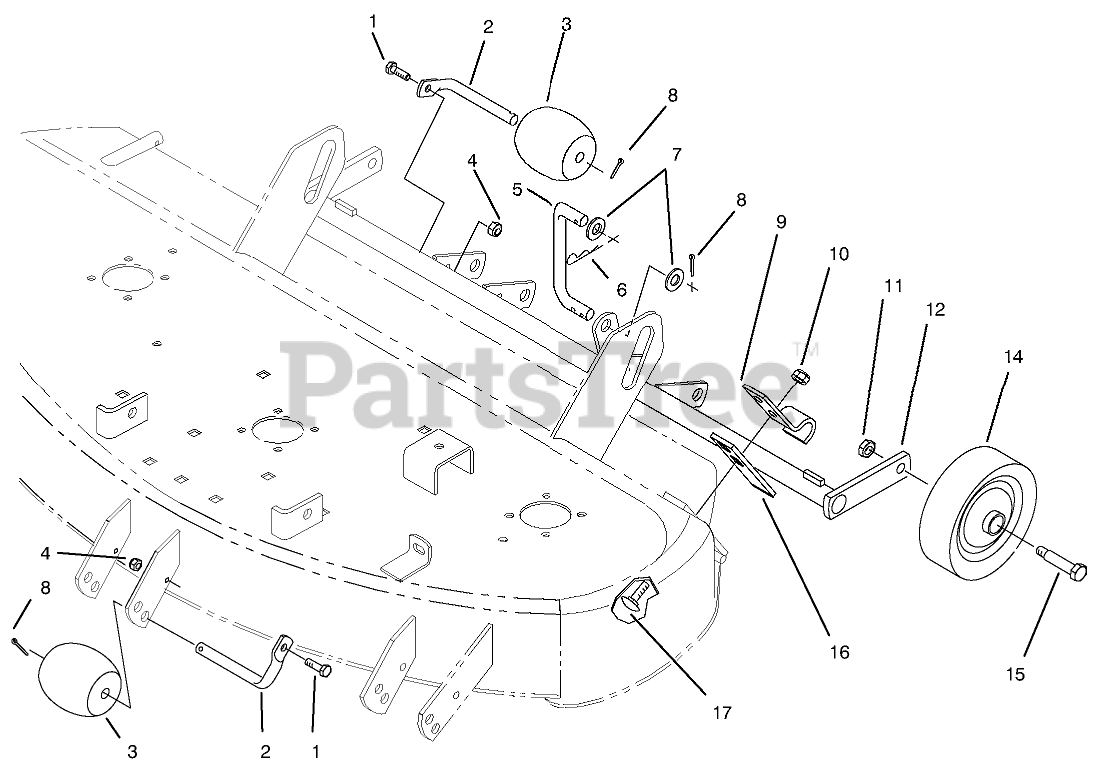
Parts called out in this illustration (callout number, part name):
1	SCREW-HH
2	SHAFT-ROLLER
3	ROLLER
4	NUT-LOCK, NI
5	LINK-REAR
6	Hairpin
7	WASHER-FLAT
8	PIN-COTTER
9	Clamp
10	NUT-LOCK, NI
11	NUT-HEX
12	SUPPORT-GAGE WHEEL
14	WHEEL
15	BOLT-SHOULDER
16	Bar
17	SCREW-CARR
